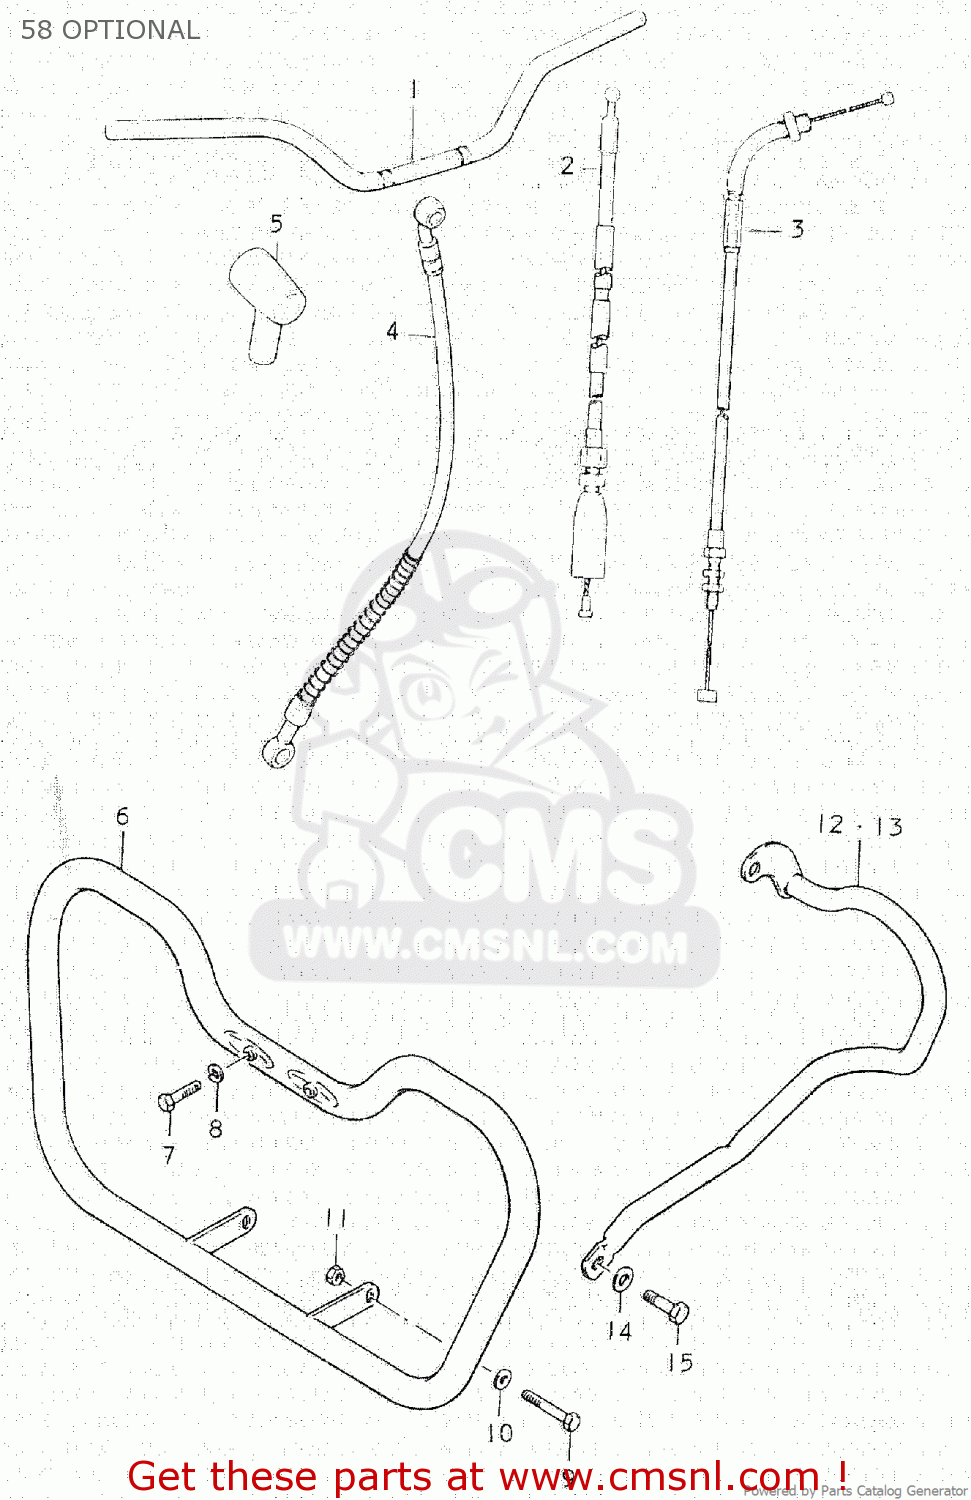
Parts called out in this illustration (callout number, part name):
1	HANDLEBAR
2	CLUTCH CABLE
3	CABLE THROTTLE
4	HOSE,FRONT BRAKE
5	BOOT
6	BUMPER FRONT
7	BOLT 8X45
8	LOCK WASHER
9	BOLT
10	WASHER
11	NUT
12	BUMPER, RH REAR
13	BUMPER, LH REAR
14	WASHER (10.1X21X2.3)
15	BOLT(10X45)
